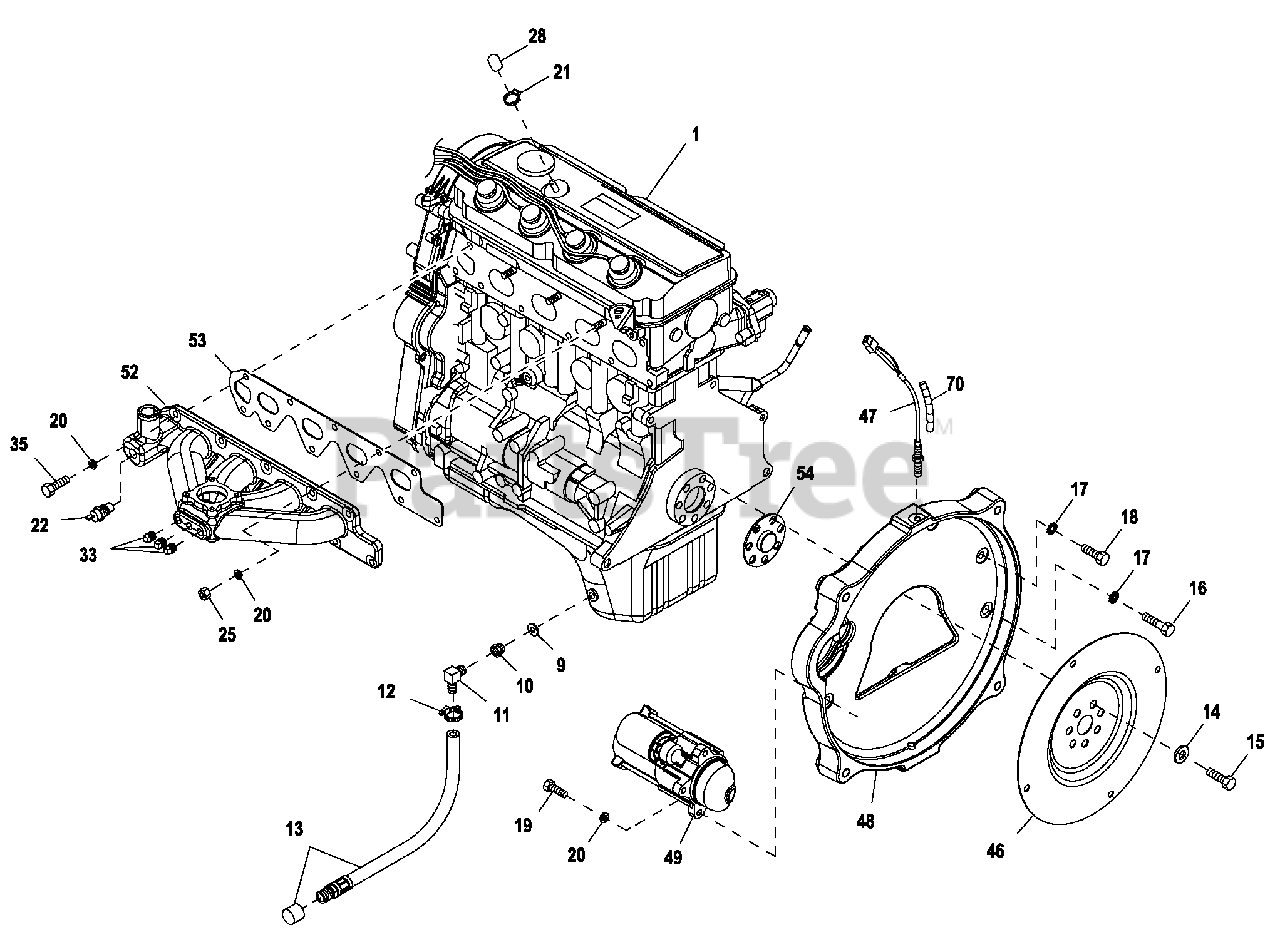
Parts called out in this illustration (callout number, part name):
1	ENGINE 2.4L G2 CERTIFIED
9	WASHER NYLON .565
10	ADAPTER M14-1.50 X 3/8 NPT
11	BARBED EL 90 3/8 NPT X 3/8
12	CLAMP HOSE .38-.87
13	HOSE DRAIN ASSY 28"
14	WASHER FLAT .531 ID X 1.062 OD
15	SCREW HHC M12-1.25 X 20 G10.9
16	SCREW HHC M10-1.25 X 45 G8.8
17	WASHER SHAKEPROOF EXT 7/16 STL
18	SCREW HHC M10-1.25 X 30 G8.8
19	SCREW SHC M8-1.25 X 30 G12.9
20	WASHER LOCK M8-5/16
21	CLAMP HOSE #6 .43-.78
22	TEMPERATU RE SENDER
25	N U T HEX M8-1.25 G8 CLEAR ZINC
28	CAP ANTIFREEZE R UBBER 9.5DIA
33	PL U G STD PIPE 1/4 STEEL SQ HD
35	SCREW HHC M8-1.25 X 25 G10.9
46	FLEX PLATE 2 POLE 2.4L G2
47	ASSY MAGPICK U P(3/8-24 MALE)
48	ADAPTER ENGINE 2.4L MACHINE
49	MOTOR STARTER
52	MANIFOLD INTAKE (MACHINED)
53	GASKET INTAKE MANIFOLD
54	SPACER 2.4L G2 FLEX PLATE
70	CONDUIT FLEX .25"ID
